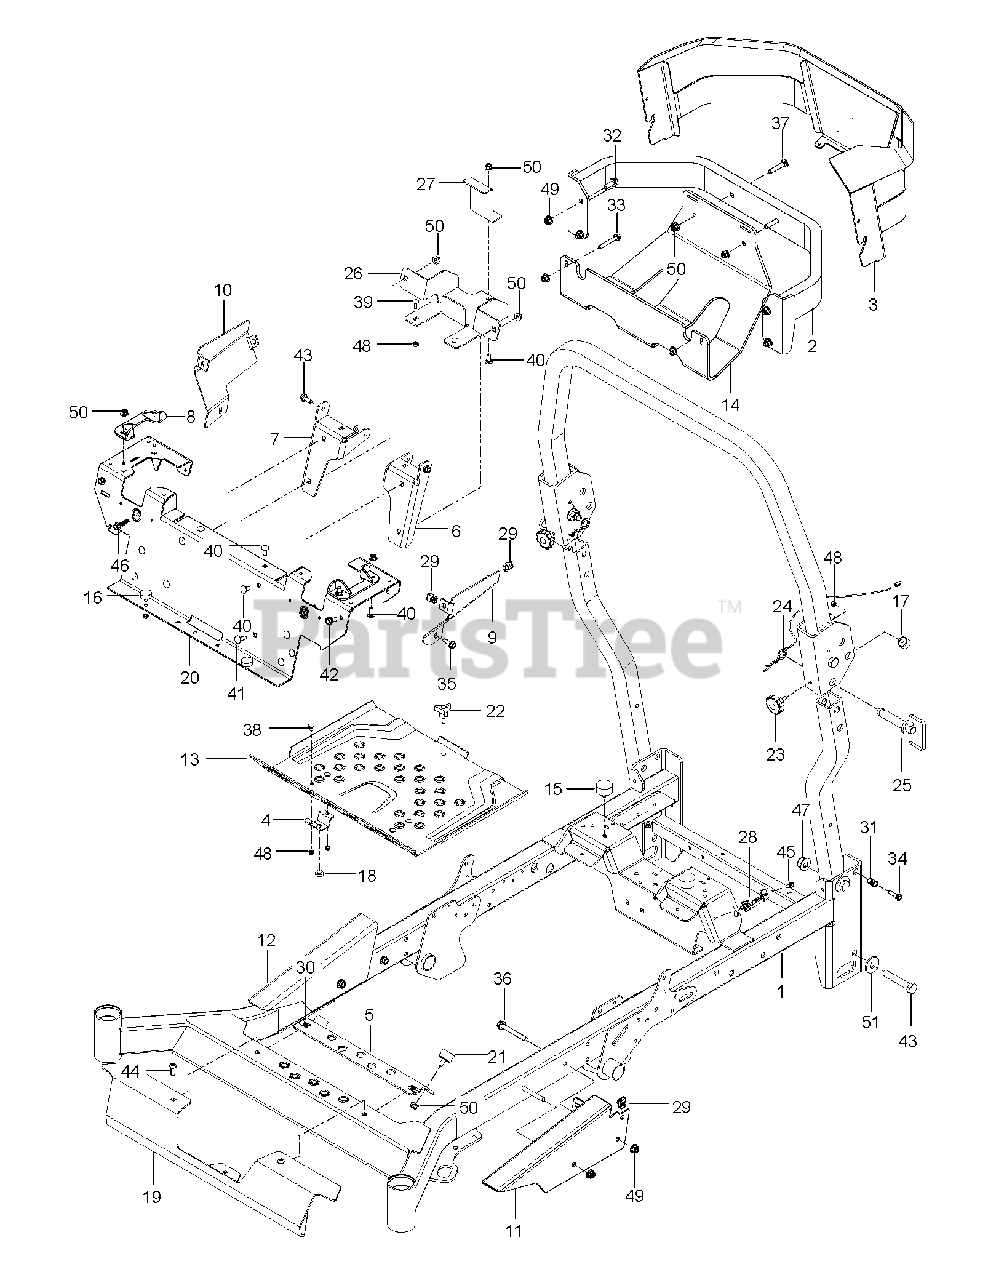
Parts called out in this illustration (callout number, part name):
1	FRAME.W/DECALS.72".ORG
2	BUMPER REAR LONG UNPAINTED
3	GUARD.PNT.ENGINE.GREY
4	COVER.PNT.VALANCE.PZ.GREY
5	BRACKET.PNT.ISOLATOR.SUPPT.BLK
6	BRACKET.PNT.MTG.SEAT.LH.EDIP
7	BRACKET.PNT.MTG.SEAT.RH.EDIP
8	CABLE.YOKE.PARK.BRAKE
9	PANEL.PNT.CLOSE.OUT.LH.ORG
10	PANEL.PNT.CLOSE.OUT.RH.ORG
11	PANEL.PNT.WEDGE.LH.ORG
12	PANEL.PNT.WEDGE.RH.ORG
13	PLATE.PNT.FOOTREST.PZ.ORANGE
15	BUMPER 5/16-18
16	BUMPER, 1/4-20 STUD, 1/4
17	BUMPER, MALE STUD, 1/4-20
18	GROMMET, BUMPER
19	COVER.PNT.VALANCE.PZ.GREY
20	CROSS.MEMBER.PNT.SEAT.FRONT.OR
21	ISOLATOR.PZ.FOOTREST
22	KNOB W/STUD
23	NUTSERT 5/16-18 THICK GRIP
24	PIN HAIR .148 X 2-15/16 #210
26	PLATE.PNT.BATTERY.EDIP
27	BRACKET.PNT.MOUNT.BATTERY.EDIP
28	BRACKET.FUSE.RELAY.HOUSING.PZ
29	U-CLIP 5/16-18 NUT RETAINER
30	SCREW.BUTTON.HEAD.TORX.3/8-161
31	HHFS 3/8-16 X 3 GRD 5 ZD
32	HHFS 3/8-16 X 1 GRD 5 ZD
33	HHFS 5/16-18 X 2.25 GD 5
34	HHFS 5/16-18 X 1.25 TPBLT GD 5
35	RP BLT 5/16-18 X 1 THRD FORM D
36	5/8-11 X 3-1/2 HHB GRADE 5
37	RHSNB 3/8C X 2
39	BOLT
40	BOLT 5/16C X 3/4" CARRIAGE
42	BOLT, SHOULDER
43	SCREW.SHAKEPROOF.1.25.BLACK
44	SCREW.BUTTON.HEAD.TORX.3/8-161
45	SCREW
46	JAM NUT 1/4C (2 2 PW01)
47	NUT 5/8-11 FLG NYLOC ZD
48	RP_NUT 1/4-20 NYLOC
49	NUT 3/8-16 HEX FLG NYLOC ZD
50	5/16-18 NYLOC FLANGE NUT
51	WASHER, 5/8 FLAT
